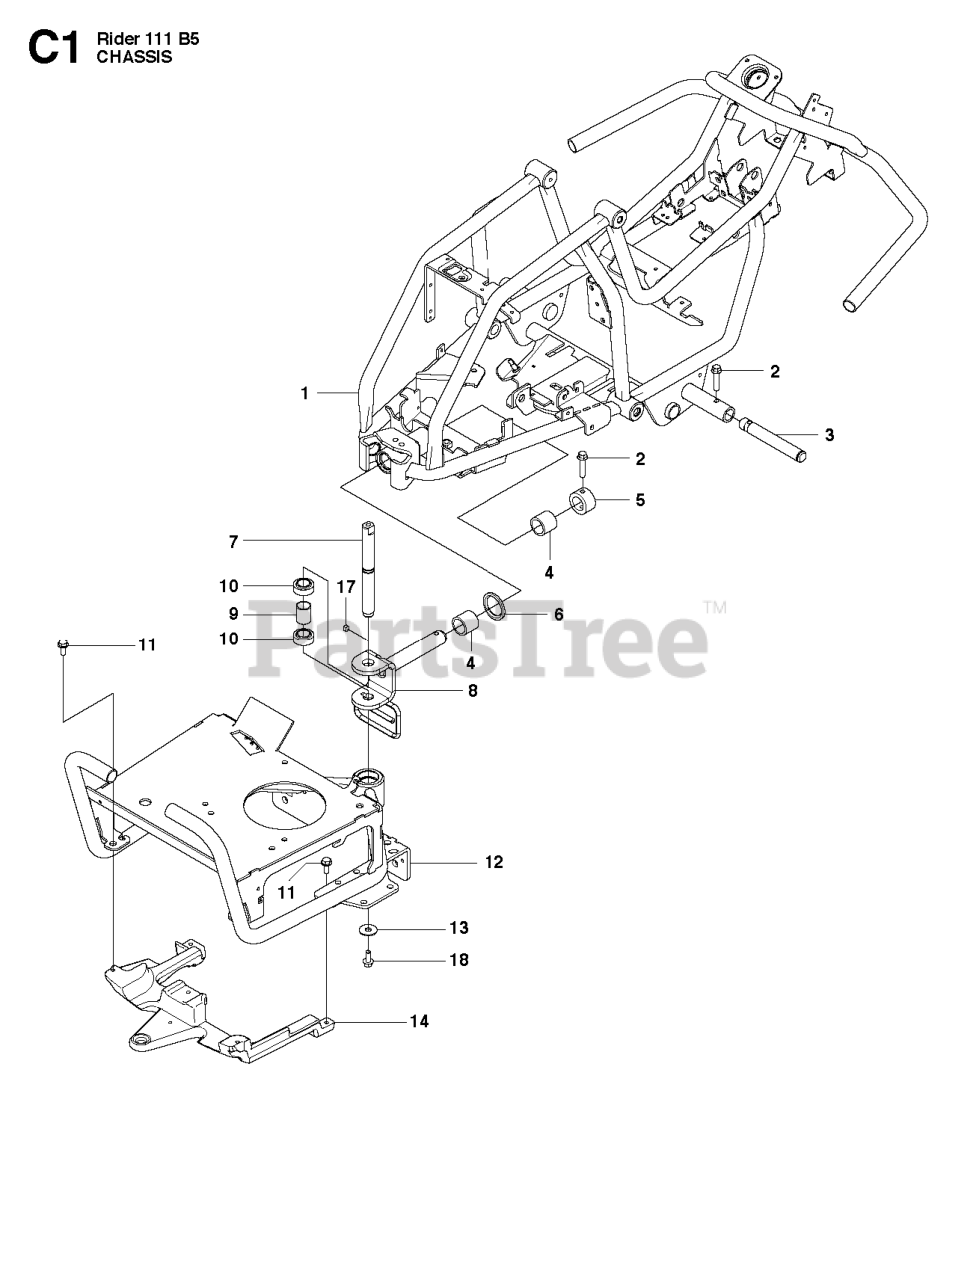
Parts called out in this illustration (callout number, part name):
2	BOLT FLANGE - M8X40\
4	BUSHING
5	STOP SLEEVE
